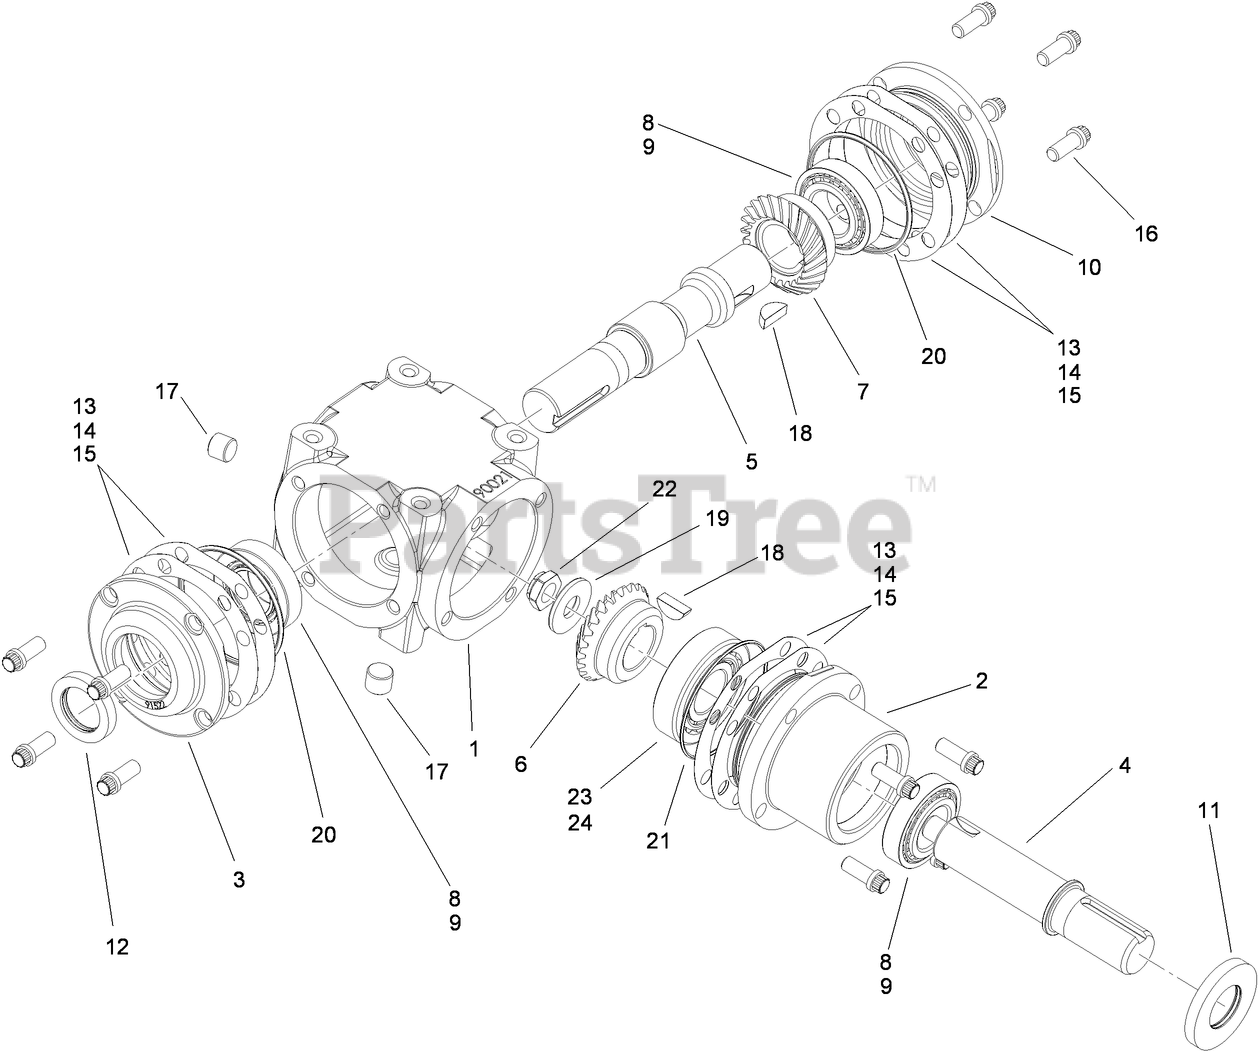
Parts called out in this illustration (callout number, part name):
2	HOUSING-PINION
3	CAP-END, OPEN
4	SHAFT-PINION
5	SHAFT-CROSS
6	GEAR-SHAFT, CROSS
7	GEAR-PINION
8	BEARING-CUP
9	BEARING-CONE
10	CAP-END, CLOSED
12	SEAL-SHAFT, CROSS
13	SHIM-BROWN, .010IN
14	SHIM-BLUE, .005IN
15	SHIM-GREEN, .003IN
18	KEY-WOODRUFF
19	WASHER
20	O-RING
21	O-RING
22	NUT LOCK
23	BEARING-CUP
24	BEARING-CONE
